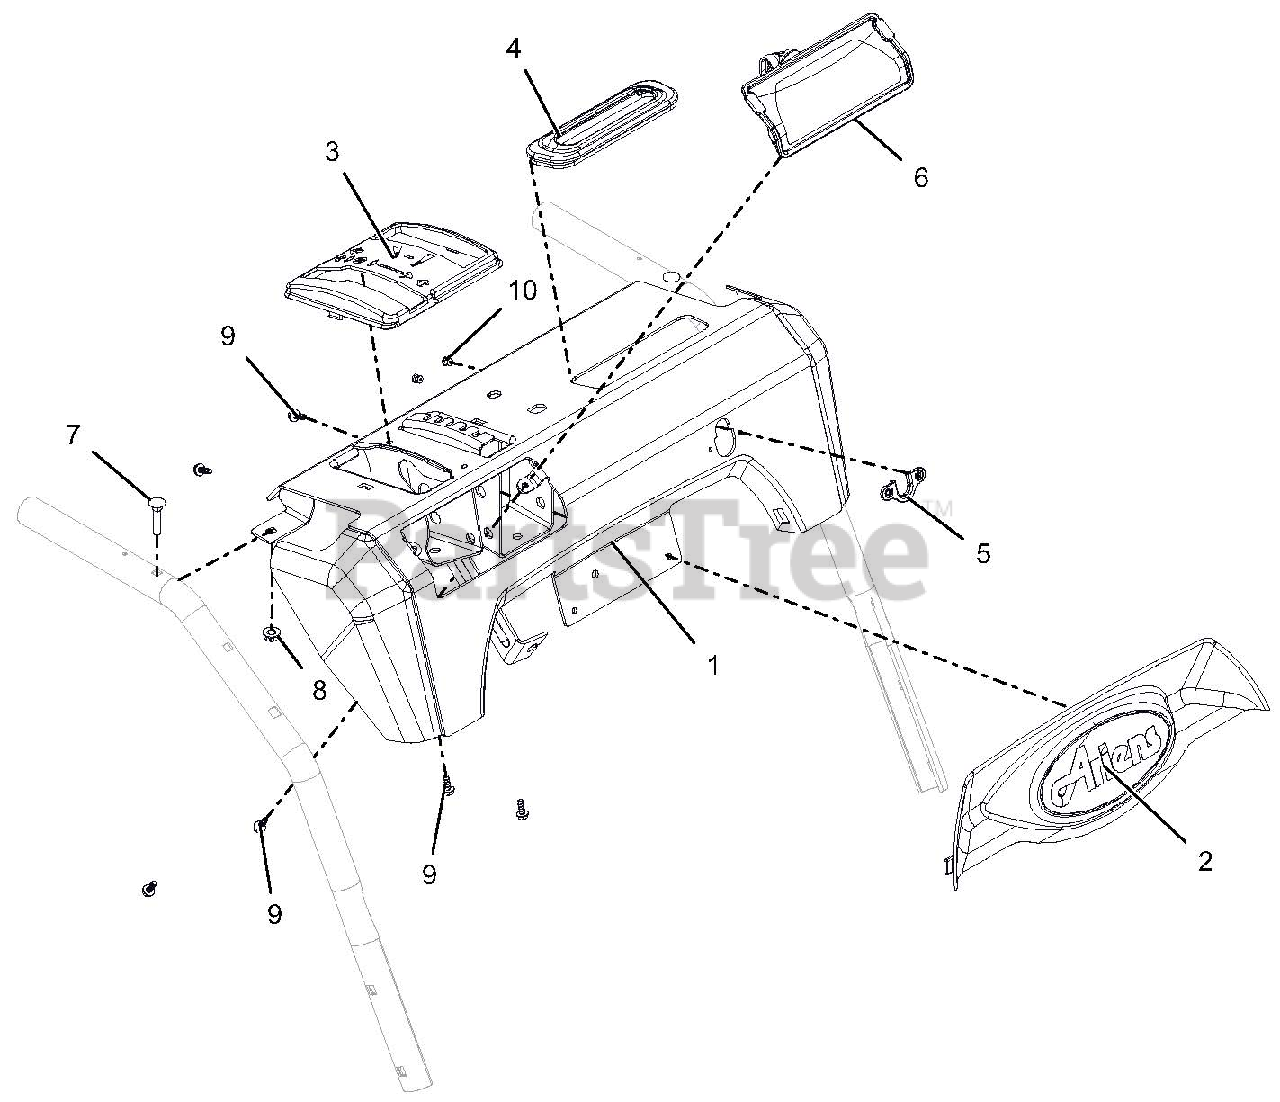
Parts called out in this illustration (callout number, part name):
1	KIT, DASH PANEL W/DECAL HYD
2	DASH BEZEL, ARIENS LOGO - PRO
3	SHIFT BEZEL W/ NEUTRAL
4	GROMMET, BOOT, QUICK TURN
5	GROMMET, CABLE, QUICK TURN 2
6	HEADLIGHT ASY, HALO 20W 2SHOT
7	BLT-RDHDXLSQNK.25-20X1.25 G5ZC
8	@NUT-LK-CTR-FLG .25-20 YWZC
9	SCR-TAP #10X.50 BOSS INDHXHD
10	RVT-POP #43 .125X.313 STL ZINC
